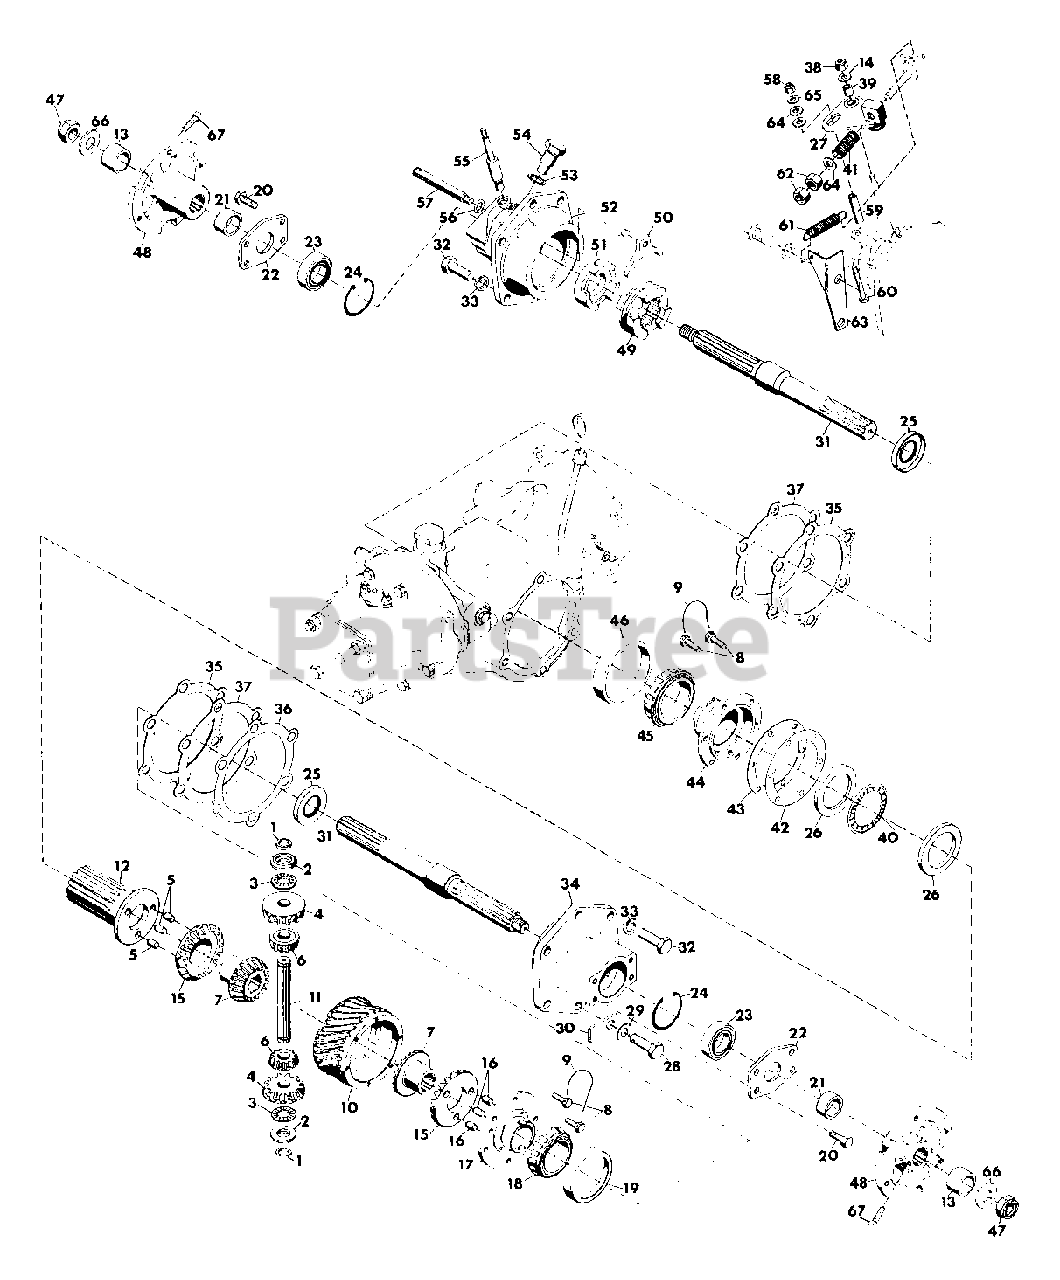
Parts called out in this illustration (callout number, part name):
1	Ring, Retaining .750 Shaft
2	Spacer .765x1.245x.200
3	Bearing, Needle Thrust .752x1.240x.078
4	Gear, Differential Shifting Bevel
5	Pin, Dowel .375x.375
6	Gear, Spider Bevel
7	Gear, Differential Bevel
8	Bolt, Special 5/16-18
10	Gear, Worm 8 Start
11	Pin, Spider
12	Shifter, Splined Pinned
13	Spacer
14	Washer, Flat .344x.688x.065
15	Gear, Pinned Bevel
16	Pin, Dowel .375x.500
17	Housing, Pinned
18	Core, Roller Bearing
19	Cup, Roller Bearing
20	Bolt, Hex 3/8-16x.750
21	Spacer
22	Plate, End
23	Bearing, Ball 1.000x2.000x.562
24	Ring, Retaining 2.000 Bore
25	Seal, Oil 1.188x2.000x.250
26	Race, Thrust 2.00x2.740x.031
27	Arm, Shifter
28	Bolt, Hex 1/2-13x1 Nylon Insert
29	Washer, Flat .531x1.062x.095
30	Washer, Oil Brain
31	Axle, Straight
32	Bolt, Hex 1/2-13x1
33	Washer, Lock 1/2 SP
34	Housing, Axle
35	Gasket, Axle Housing
36	Shim, Axle Housing .005
37	Shim, Axle Housing .020
38	Nut, Lock 5/16-18
39	Bushing, Nylon .375x.503x.875
40	Race, Bearing Thrust .060
41	Spring, Compression 2x.720
42	Shim, Clutch Worm Gear .005
43	Shim, Clutch Worn Gear .020
44	Housing, Clutch
45	Cone, Roller Bearing
46	Cup, Roller Bearing
47	Nut, Hex 3/4-10 Light Thin
48	Hub, Wheel
49	Clutch, Shifting
50	Yoke, Shifting
51	Clutch, Stationary
52	Housing, Axle 2-Speed
53	Washer, Oil Strainer Nut
54	Bolt, Stationary Clutch
55	Pivot, Stationary
56	O-Ring .438x.625x.094
57	Pin, Clutch Sliding
58	Nut, Lock 1/4-20
59	Bushing
60	Bolt
61	Spring, Extension 2.50x.62
62	Nut, Jam 3/8-24 Hex
63	Bracket, Spring 2-Speed
64	Washer, Flat .406x.812x.065
65	Washer, Flat .281x.625x.065
66	Washer, Flat .812x1.469x.134
67	Screw, Set 7/16-14x1.00
